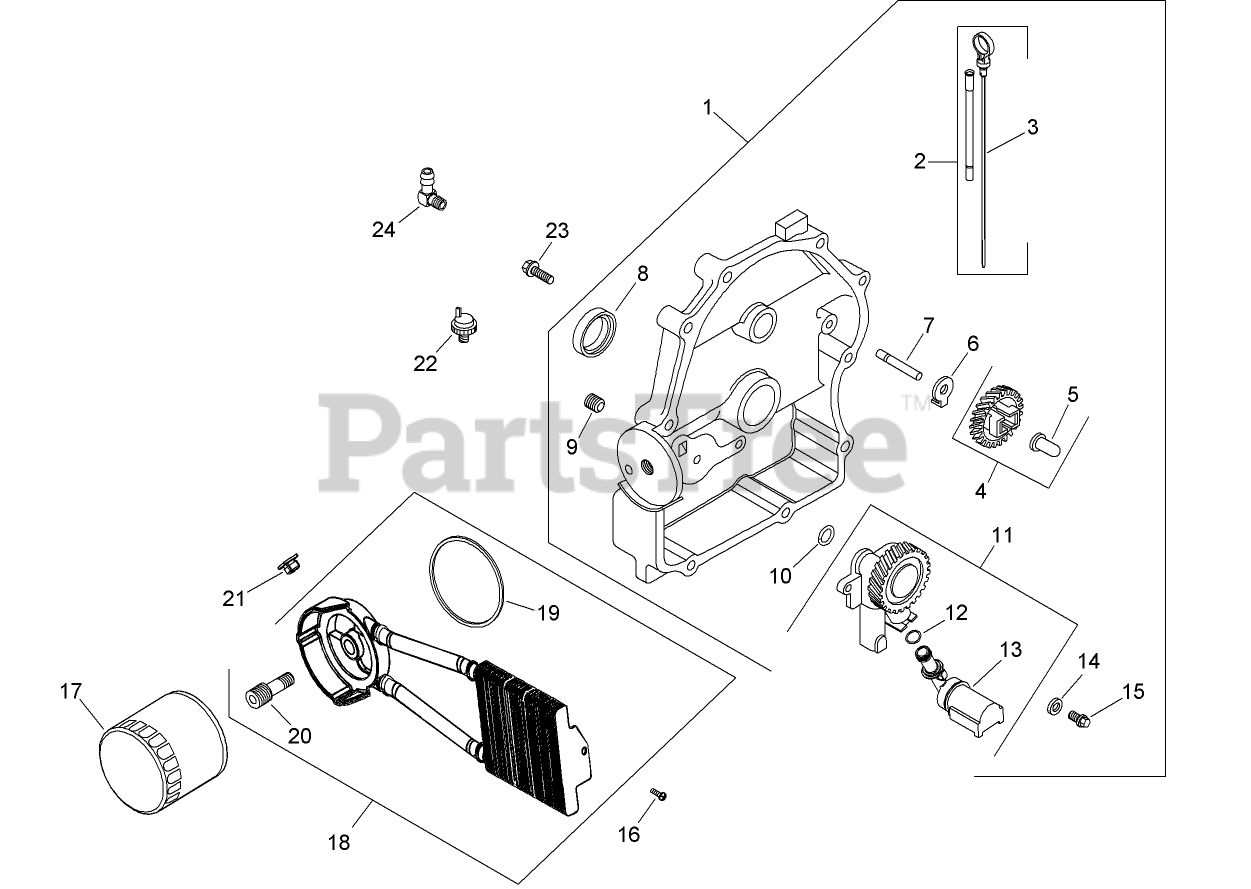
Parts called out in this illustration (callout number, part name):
1	CLOSURE PLATE ASM (INCLUDES REF 2-15)
2	Dipstick Tube ASM (INCLUDES REF 3)
3	Dipstick
4	GOVERNOR GEAR KIT (INCLUDES REF 5)
5	PIN-REGULATING, GOVERNOR
6	TAB-LOCKING
7	SHAFT-GEAR, GOVERNOR
8	Seal-Oil (PTO End)
9	PLUG-PIPE, COUNTERSUNK (1/8)
10	O-Ring
11	OIL PUMP ASM (INCLUDES REF 12,13)
12	O-RING (OIL PICK-UP)
13	TUBE-PICK UP, OIL
14	WASHER-FLAT (6 MM)
15	SCREW-FLANGE, THREAD FORMING (M6X1.0X25)
16	SCREW-TAP (M6X1.7X18)
17	Filter-Oil
18	OIL COOLER KIT (METAL)
19	O-RING (OIL COOLER)
20	NIPPLE (OIL FILTER)
21	Nut-Plastic
22	SWITCH-PRESSURE, OIL
23	SCREW-FLANGE (M8X1.25X45)
24	Connector-Hose, 90 Deg
